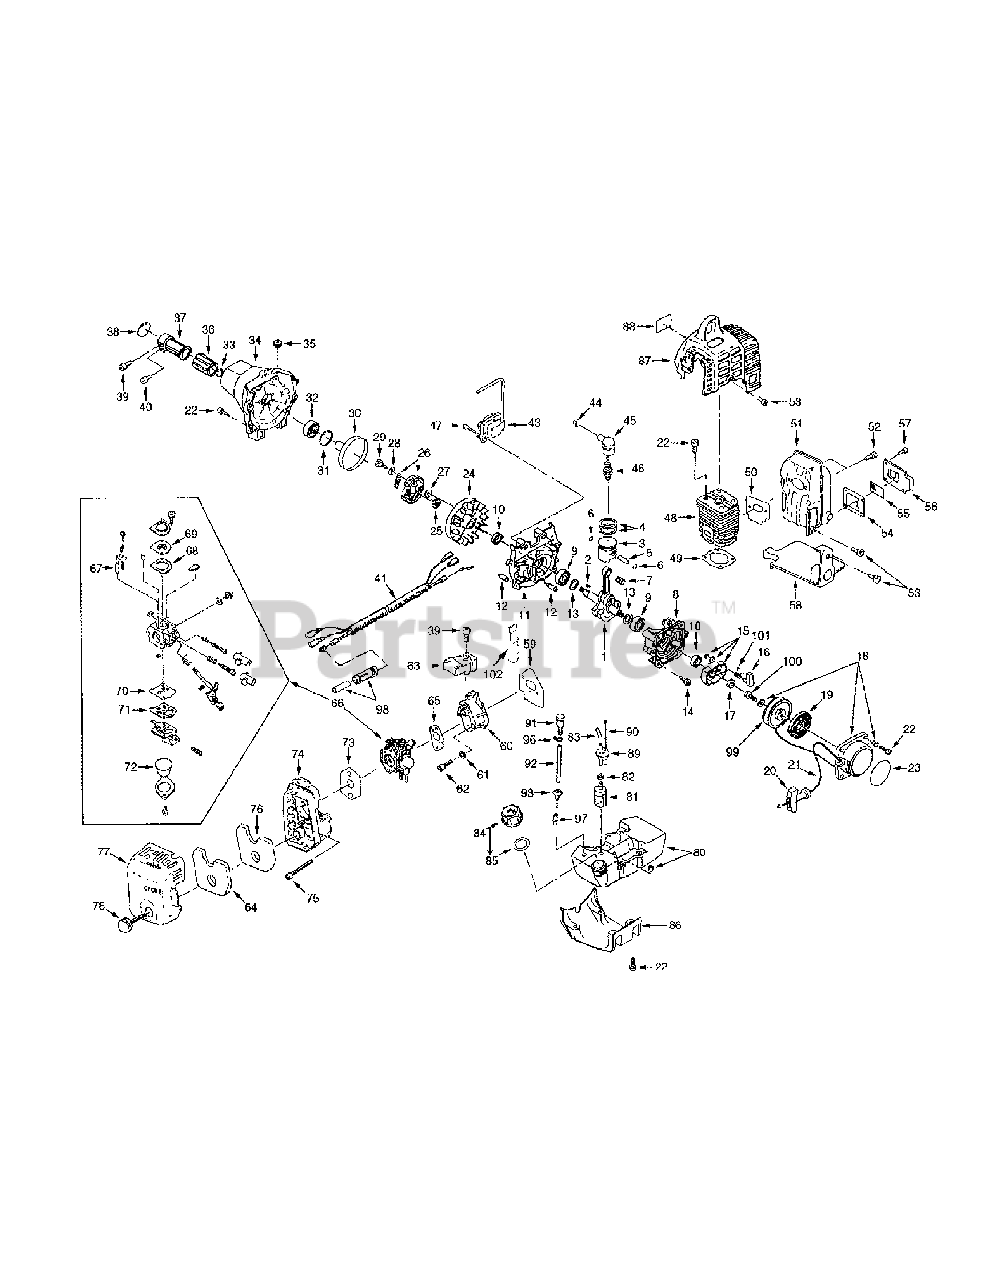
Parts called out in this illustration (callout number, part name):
3	Piston Assembly
4	Ring, Piston
6	Clip, Piston Pin
7	Bearing, Needle
8	Crankcase Assembly
9	Bearing, Ball, 6201
11	Crankcase Assembly
13	Shim, 0.1 mm
13	Shim, 0.2mm
15	Pulley Assembly, Starter
18	Recoil Assembly
19	Spring, Spiral
20	Knob, Starter
21	Rope, Starter
24	Flywheel, Magneto
26	Clutch Assembly
30	Drum, Clutch
31	Snap Ring, R-35
32	Bearing, Ball, 6202ZZ
33	Snap Ring, S-15
34	Housing, Blower
38	Snap Ring, R-47
41	Wire Complete, Throttle
43	Coil Assembly, Ignition
46	Spark Plug
49	Gasket, Cylinder
50	See Ref.95 - Gasket, Muffler
54	See Ref.95 - Gasket, Baffle Plate
56	Baffle Plate, Outer
58	Baffle Plate
59	See Ref.95 - Gasket, Insulator
61	Washer
64	Element "B", Air Filter
65	See Ref.95 - Gasket
66	Carburetor Assembly
67	Valve, Float
69	Diaphragm, Metering
70	Diaphragm, Pump
73	See Ref.95 - Gasket, Air Silencer
74	Case, Air Silencer
76	Element "A", Air Filter
77	Cap, Case
81	Filter, Fuel
83	Hose
84	Cap Assembly, Fuel Tank
87	Cowling, Cylinder
90	Hose
91	Valve, Reversing
95	Gasket Kit
101	Spring, Return
